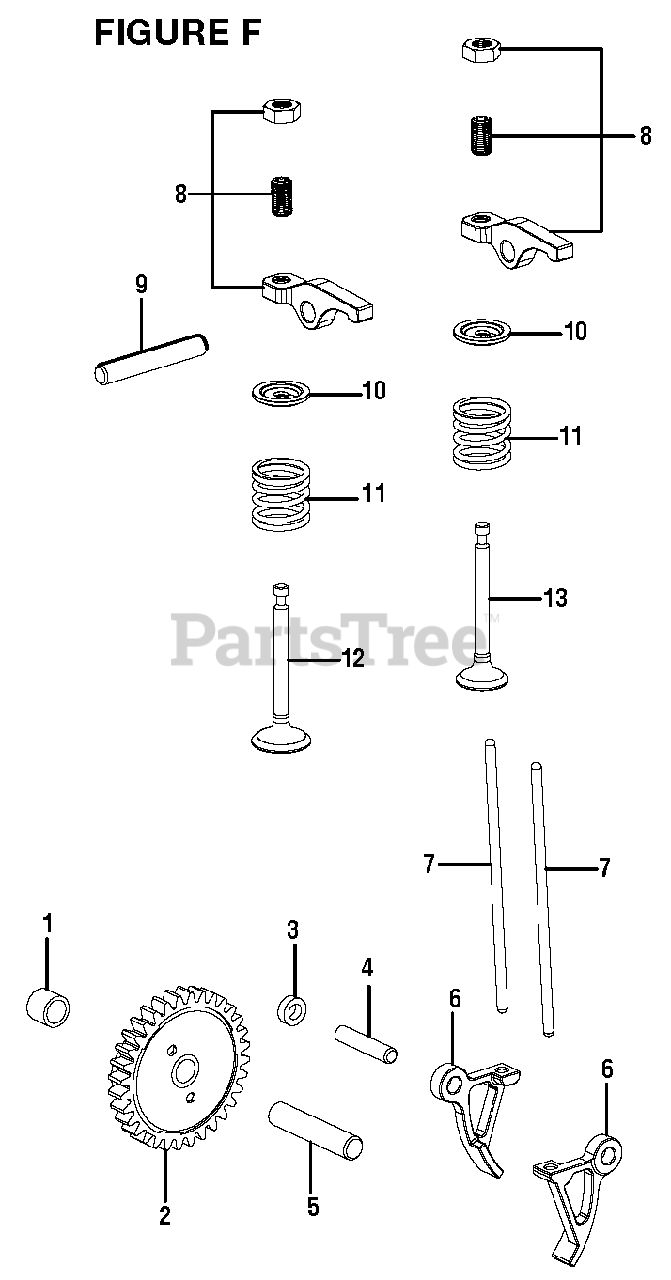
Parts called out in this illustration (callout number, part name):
3	Rocker Gasket
4	Pin (G4 x 20 mm)
5	Pin (G6 x 30 mm)
8	Upper Rocker Assembly
9	Pin (G6 x 32 mm)
10	Valve Spring Seat
13	Exhaust Valve
